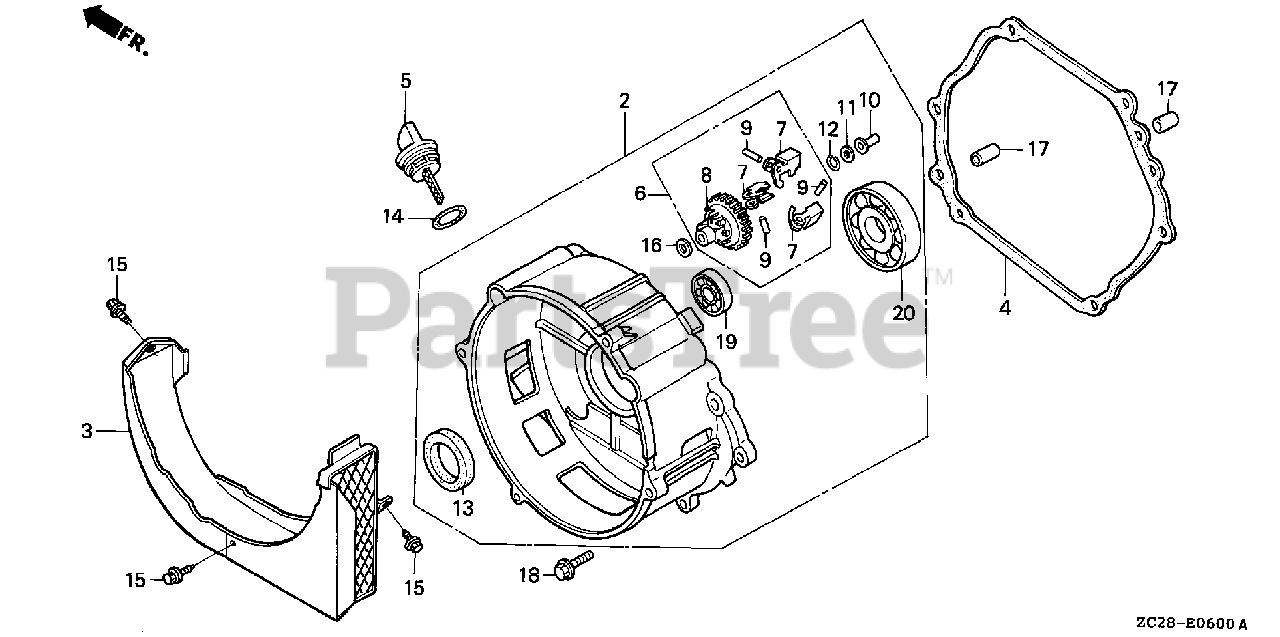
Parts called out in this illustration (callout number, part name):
2	COVER ASSY., CRANKCASE (E-TYPE)
2	COVER ASSY., CRANKCASE (E-TYPE) (NOT AVAILABLE)
2	COVER ASSY., CRANKCASE
3	COVER, DUCT
4	GASKET, CASE COVER
5	CAP, OIL FILLER
6	GOVERNOR ASSY.
7	WEIGHT, GOVERNOR
8	HOLDER, GOVERNOR WEIGHT
9	PIN, GOVERNOR WEIGHT
10	SLIDER, GOVERNOR
11	WASHER (6X16)
12	CLIP, GOVERNOR HOLDER
13	OIL SEAL (35X52X8)
14	O-RING (26X2.7)
15	SCREW, TAPPING (5X10)
16	WASHER, PLAIN (6MM)
17	PIN, DOWEL (8X12)
17	PIN A, DOWEL (8X12)
18	BOLT, FLANGE (8X40)
19	BEARING, RADIAL BALL (6202)
20	BEARING, RADIAL BALL (6207)
